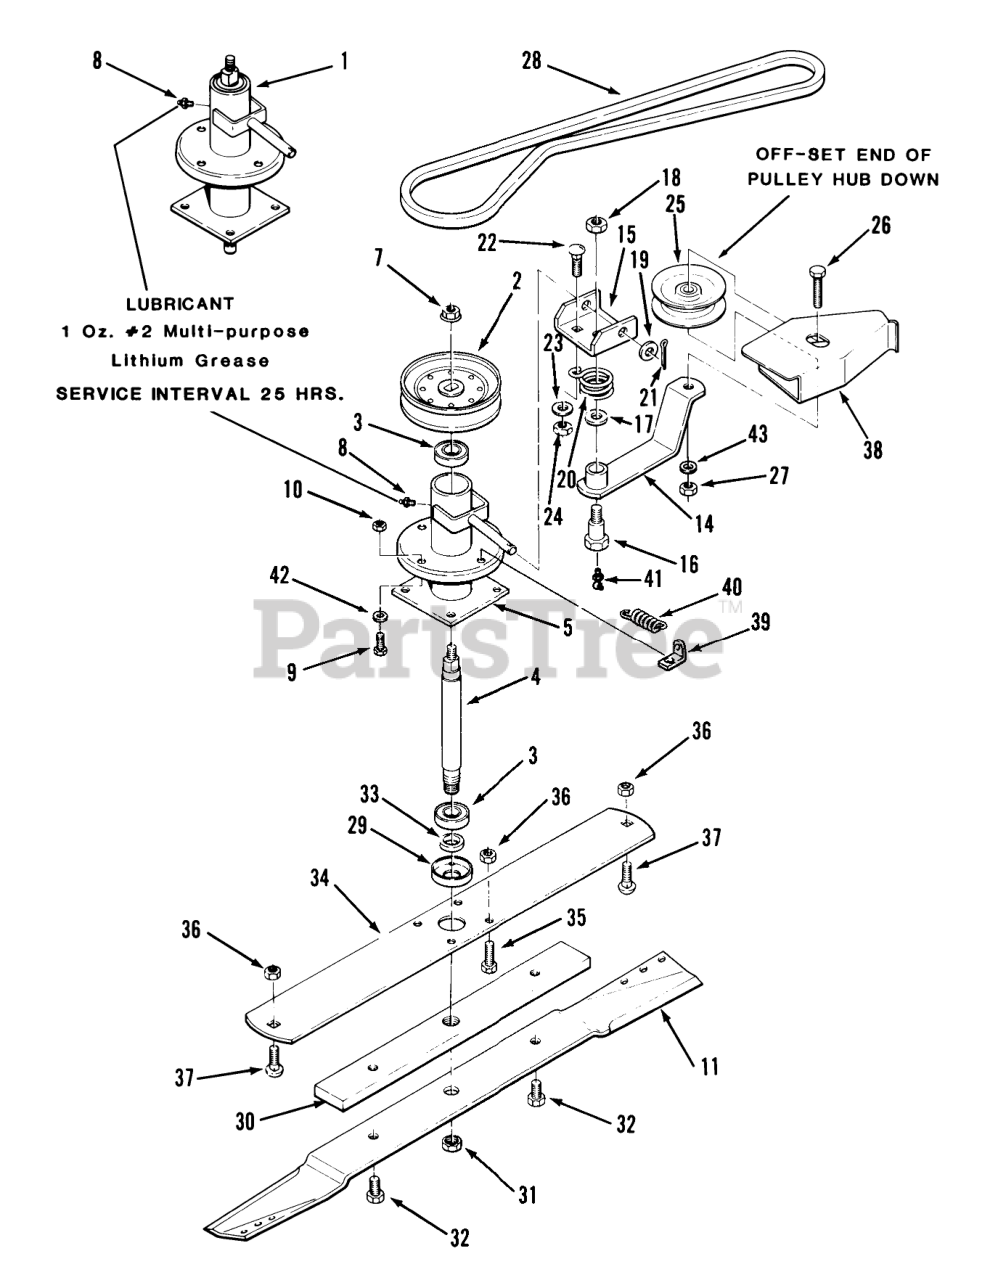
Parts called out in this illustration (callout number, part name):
1	Spindle Complete (includes items 3, 4, 5, 6 & 8)
2	PULLEY SPINDLE
3	BALL BEARING
4	SHAFT SPINDLE
5	ASS'Y-BLADE HOUSI R
7	NUT 3/8-24 WHIZLOCK
8	Zerk
9	Bolt
10	Nut
11	S/A-30' BLADE ASM
14	ASSY LEVER R
15	CHANNEL PIVOT R
16	SHOULDER BOLT
17	WASHER
18	NUT-JAM(7/16-14)
19	Washer
20	SPRING-TORSION
21	Cotter Pin
22	Bolt
23	Washer
24	NUT
25	PULLEY IDLER R
26	Bolt
27	NUT
28	Mower Drive Belt
29	CUP SPINDLE
30	BAR BLADE R
31	Jam Nut
32	HEX BOLT 1/2-13X3/4
33	SPACER-BLADE
34	PLATE SUPPORT R
35	BOLT
36	NUT
37	Carriage Bolt 3/8-16 X 3/4
38	COVER BELT R
39	CLIP - SPRING
40	SPRING-EXTENSION
41	ZERK 90DEGREE
42	Lockwasher
43	WASHER
